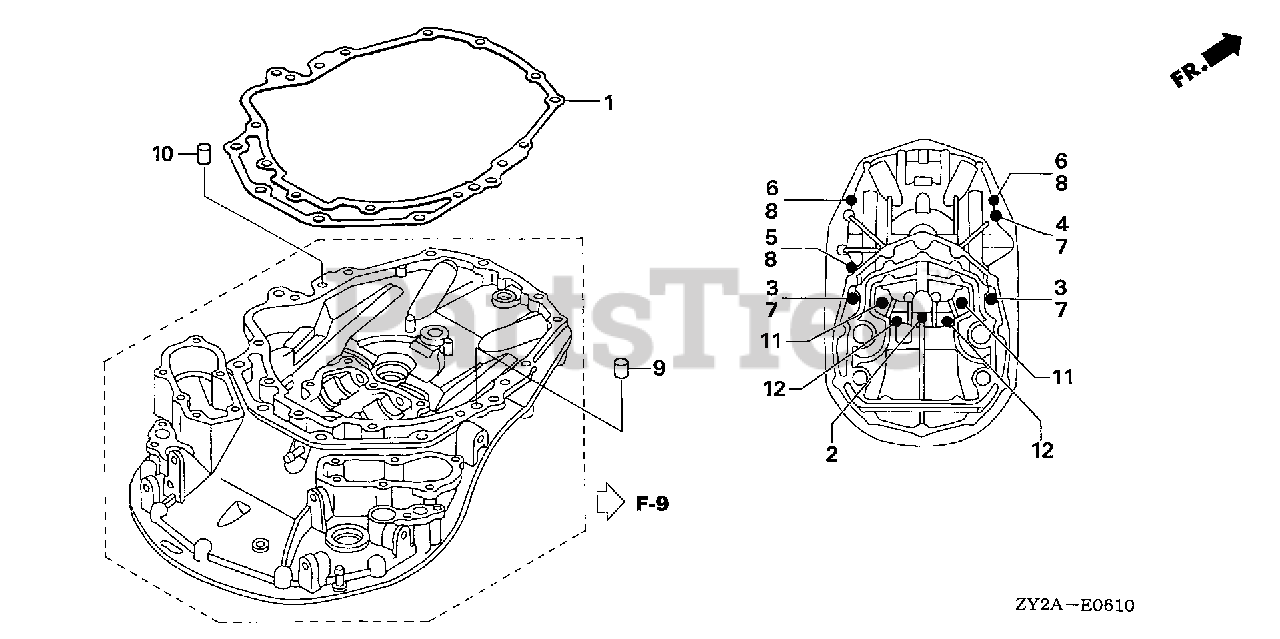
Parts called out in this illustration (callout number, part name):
1	GASKET, MOUNT CASE
2	BOLT, FLANGE (10X120) (SATO)
3	BOLT, HEX. (12X120)
4	BOLT, HEX. (12X65)
5	BOLT, HEX. (10X85)
6	BOLT, HEX. (10X60)
7	WASHER, PLAIN (12MM)
8	WASHER, PLAIN (10MM)
9	PIN, DOWEL (14X15)
10	PIN B, DOWEL (10X16)
11	BOLT, FLANGE (10X70)
12	BOLT, FLANGE (12X120)
